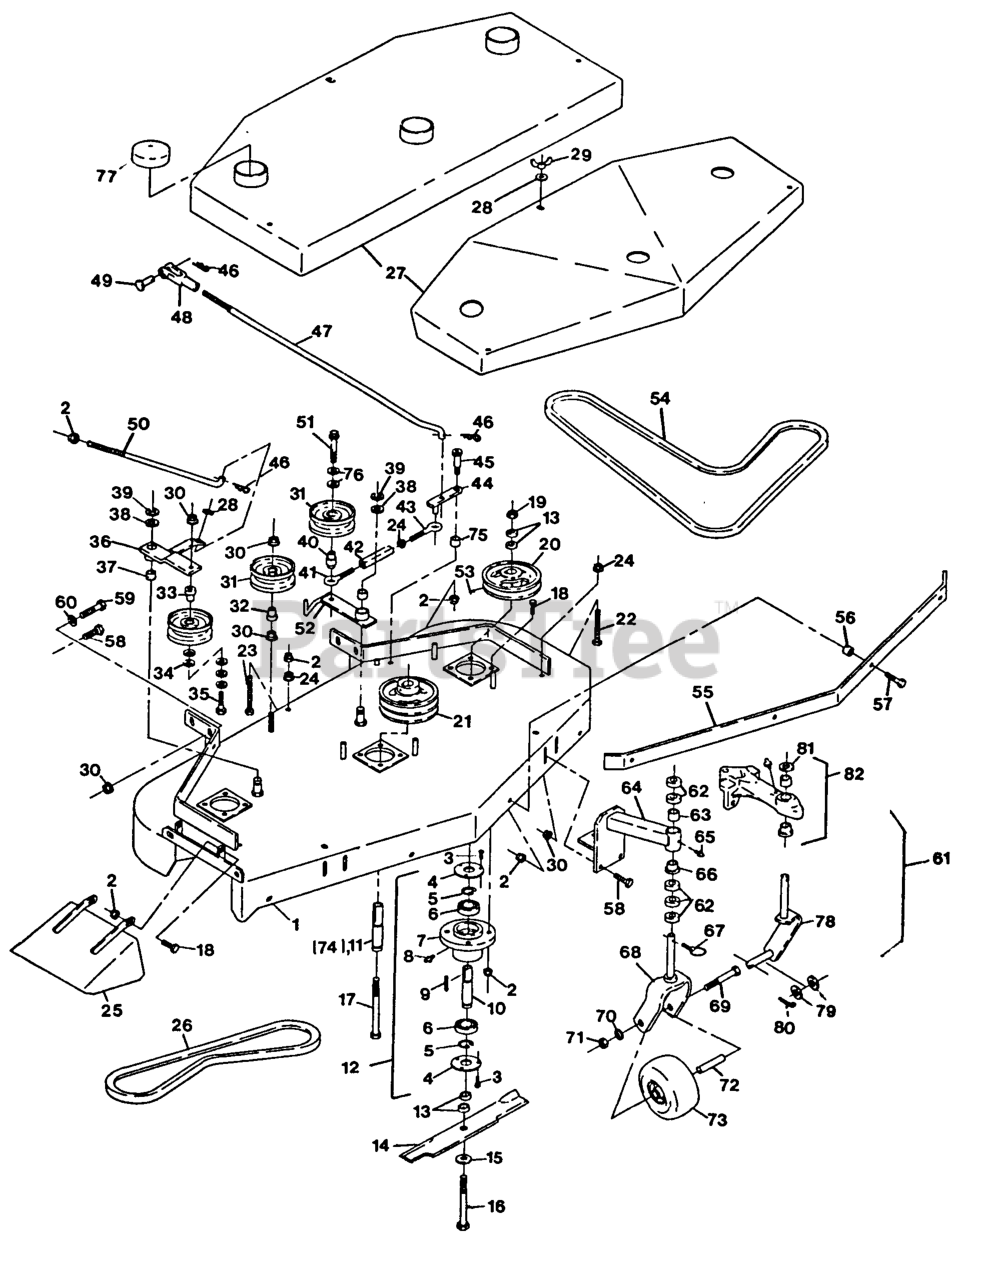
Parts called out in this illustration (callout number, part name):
3	SCRWMACH PHS
7	HOUSING,CUTTER
10	SPINDLE,CUTTER
12	HOUSING,CUTTER COMPLETE
17	SCREW-CAP, HH
20	PULLEY,CAST IRON
22	BOLT,TAP HH
23	BOLTTAP HH
26	BELT,FRONT DECK
31	IDLER,PULLEY
33	BUSHING-IDLER
36	ARM,IDLER COMPLETE
37	BEARING,POWDERED METAL
38	WASHER-SPINDLE
40	BUSHING-ENGAGEMENT
41	EYEBOLT-THREAD, LH
42	BODY-TURNBUCKLE
43	EYEBOLT-THREAD, RH
45	BOLT,SHLDR KSKH
46	PIN-COTTER
48	YOKE-ADJUSTABLE
49	PIN-CLEVIS
50	ROD,BELT TENSION
53	SCREW-SET
54	BELT,MAIN DECK
62	SPACER-CASTER
63	BEARING,STRAIGHT
74	HOUSING,CUTTER COMPLETE
77	CAP,SPINDLE GUARD
78	WLD,STRUT CASTER
